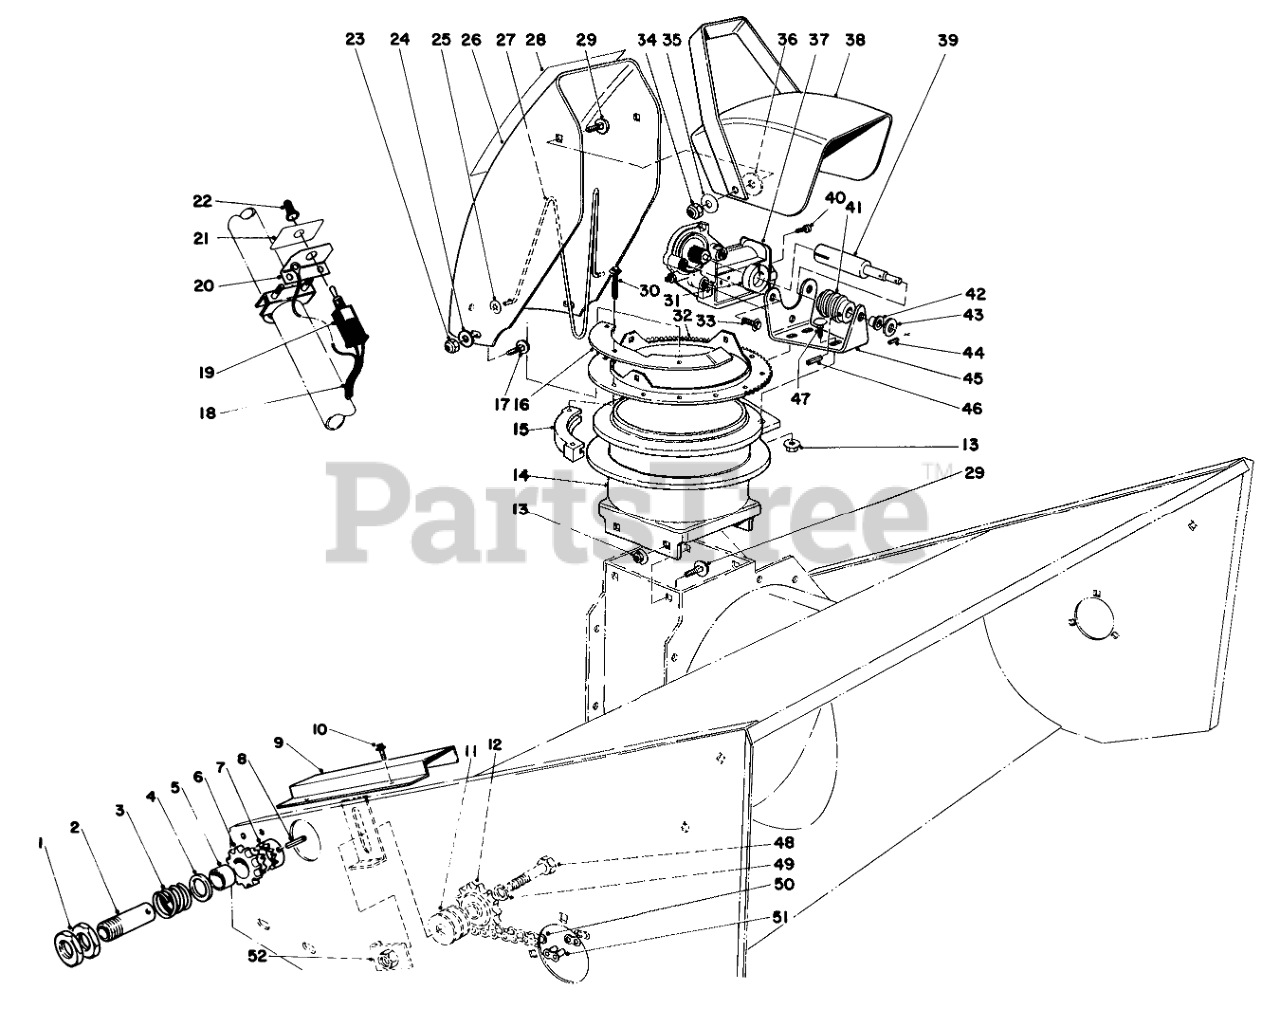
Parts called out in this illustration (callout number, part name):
1	THIN NUT
2	Clutch Sleeve
3	Spring Compression
6	Clutch Sprocket
7	Clutch Collar
8	PIN-ROLL
9	Chain Cover
10	SCREW-HWHTF
11	WASHER-FLAT
12	IDLER SPRKT (60016)
13	NUT-HHF, WHIZ
14	Chute Transition
15	RETAINER-CHUTE
16	Stop-Chute Rotator
17	SCREW-CARR
18	WIRE HARNESS
19	Toggle Switch
20	Toggle Switch Mount
21	DECAL
22	BOOT-SWITCH
23	NUT-LOCK, NI
24	WASHER-PLAIN
25	NUT-PUSH
26	Upper Chute
27	WIRE-CHUTE
28	Decal-Warning
29	SCREW-CARR
30	SCREW-SPECIAL
31	SPLIT COLLAR
32	RING - CHUTE SWIVEL
33	SCREW-HHF
34	NUT-LOCK, CONE
35	WASHER-BELLEVILLE
36	WASHER-RUBBER
37	ELEC GEAR MOTOR
38	Deflector
39	WORM GEAR SHAFT
40	SCREW-HSH
41	GEAR-WORM, CHUTE
42	FLANGE BSHG #FF-310-3
43	WASHER-FLAT
44	3/32 X 9/16 ROLL PIN
45	Motor Mount
46	PIN-SPRING
47	BOLT-CARR
48	SCREW-HH
49	WASHER-LOCK
50	ROLLER CHAIN (60023)
51	LINK-CHAIN
52	NUT PLATE WA (60095)
